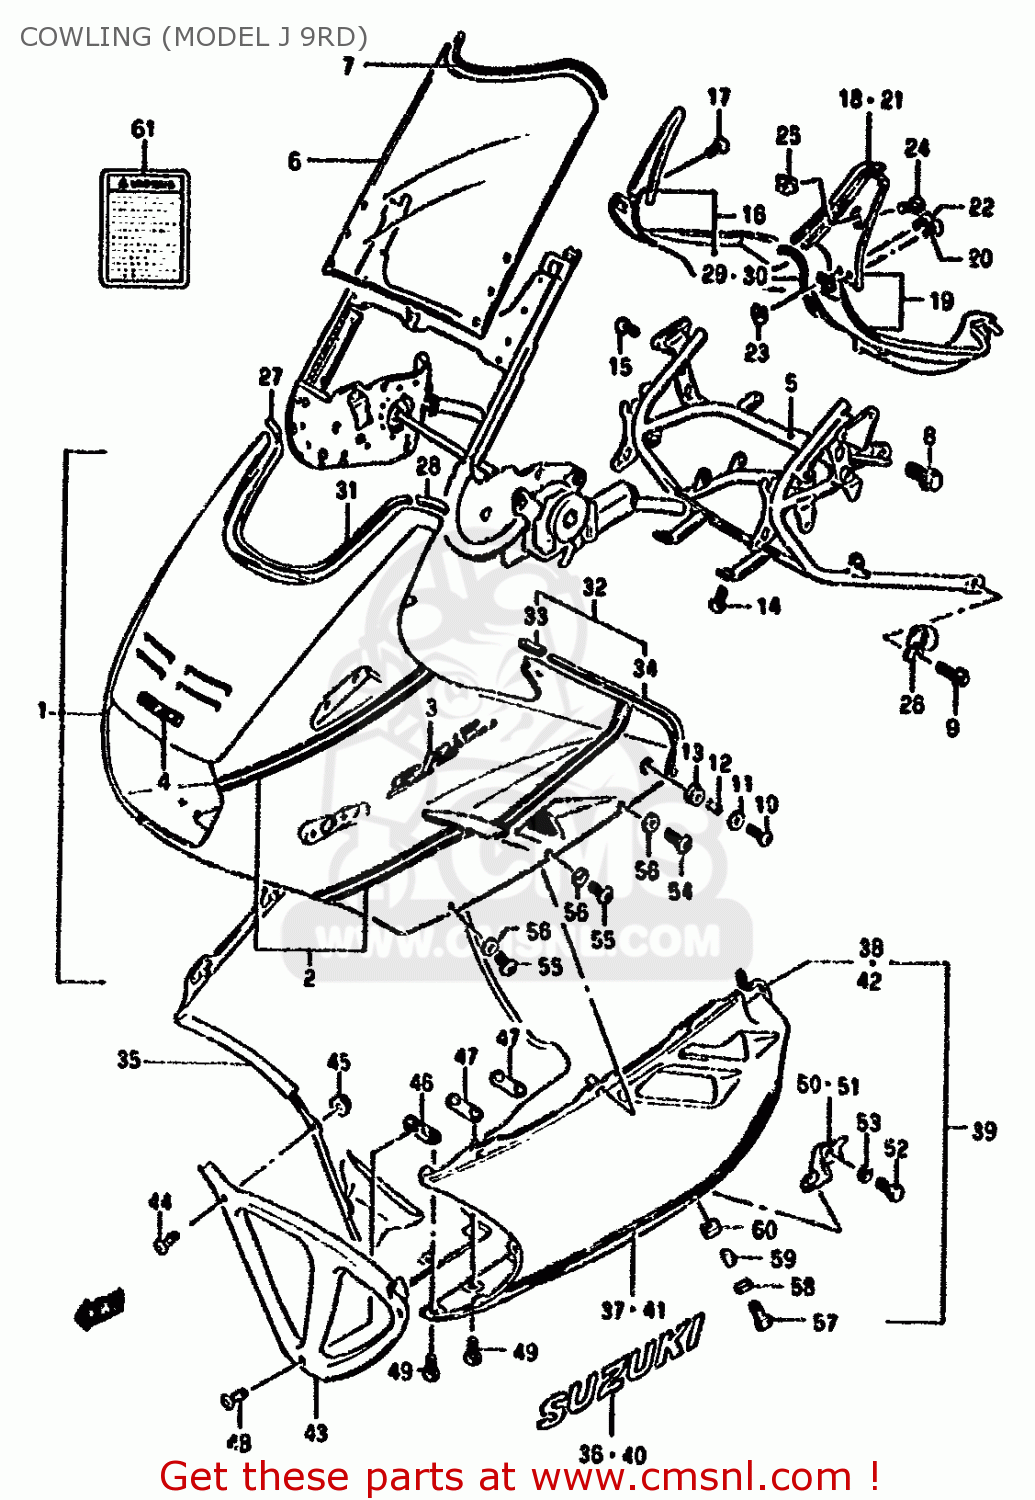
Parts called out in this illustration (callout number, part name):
1	BODY ASSY,COWLING
2	TAPE SET
3	EMBLEM (SPS)
4	EMBLEM
5	BRACE,COWLING
6	WINDSCREEN
7	MOLDING
8	BOLT(10X12)
9	BOLT
10	SCREW(6X20)
11	WASHER(6.5X18X1)
12	SPACER
13	CUSHION
14	SCREW(6X16)
15	SCREW 6X12
16	PANEL ASSY,R
17	SCREW
18	MOLDING,COWL.
19	PANEL ASSEMBLY,LEFT
20	SCREW
21	MOLDING,COWL.
22	SCREW, FRONT & REAR
23	NUT
24	SCREW
25	NUT
26	CLAMP
27	CAP,PANEL & COWLING,R
28	CAP,PANEL & COWLING,L
29	MOLDING,COWLING PANEL,R
30	MOLDING,COWLING PANEL
31	MOULDING
32	MOLDING,COWLING BODY SIDE
33	COVER,MOLDING END
34	MOLDING,COWLING BODY SIDE
35	COVER ASSY,LOWER RH (BLUE/RED)
36	EMBLEM
37	TAPE,RH
38	MOLDING,COWLING,LOWER
39	COVER ASSY,LOWER LH (BLUE/RED)
40	EMBLEM
41	TAPE,LH
42	MOLDING,COWLING,LOWER
43	COVER,COWLING,LOWER,FRONT
44	SCREW(5X14)
45	NUT
46	BRACE,COWLING LWR COVER
47	BRACE,COWLING LWR COVER RR
48	SCREW(6X12)
49	SCREW(6X16)
50	BRACE,COWLING LWR,R
51	BRACE,COWLING LWR,L
52	BOLT 8X12
53	LOCK WASHER
54	SCREW(6X20)
55	SCREW(6X16)
56	WASHER
57	SCREW(6X20)
58	WASHER(6.5X18X1)
59	SPACER(6.4X9.2X12)
60	CUSHION
61	LABEL (WARNING SCREEN)
